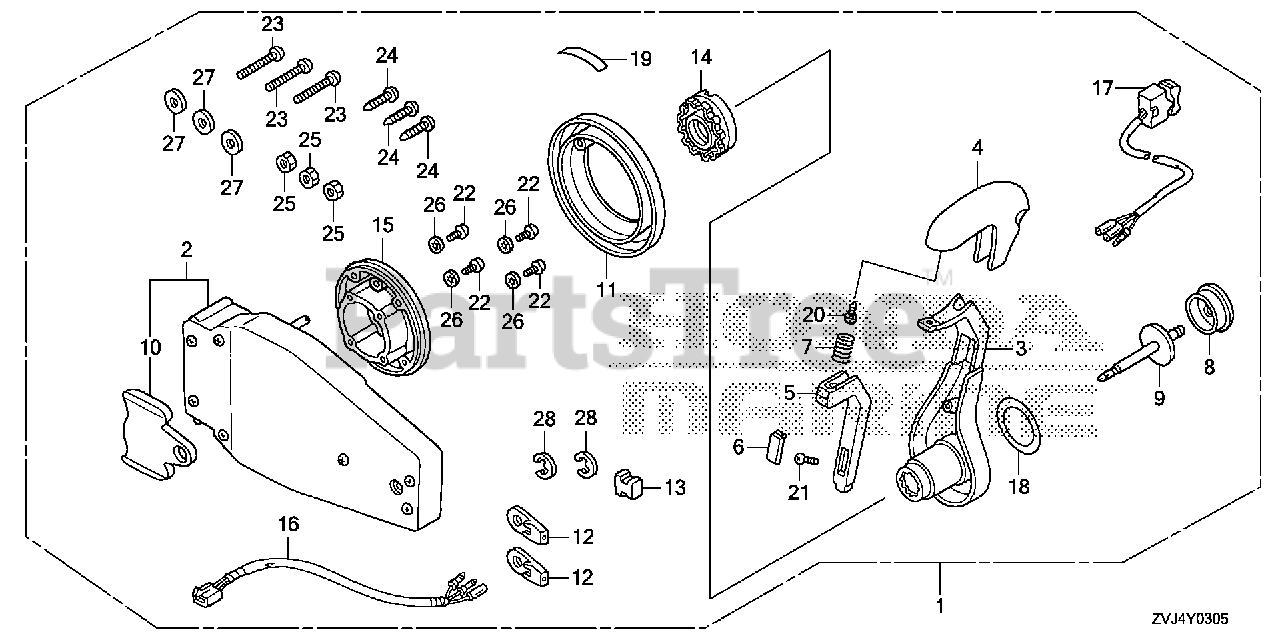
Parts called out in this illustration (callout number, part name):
1	BOX KIT, REMOTE CONTROL (FLUSH MOUNT)(L)
2	HOUSING ASSY., L. (INNER) (FLUSH MOUNT)
3	HANDLE, REMOTE CONTROL
4	COVER, GRIP
5	ARM, NEUTRAL LOCK
6	COVER, LOCK ARM
7	SPRING, NEUTRAL LOCK ARM
8	BUTTON, THROTTLE
9	SHAFT, THROTTLE BUTTON
10	PLATE, DWELL
11	COVER ASSY.
12	TERMINAL, CABLE
13	SPACER, CABLE CLAMP
14	HOLDER, NEUTRAL LOCK
15	BASE
16	SUB-HARNESS ASSY., POWER TRIM-TILT (C)
17	SWITCH ASSY., POWER TRIM-TILT (C)
18	MARK, HANDLE FLUSH MOUNT
19	MARK, FLUSH MOUNT
20	SCREW, PAN (5X16)
21	SCREW, TRUSS (4X12)
22	SCREW, PAN (5X30)
23	SCREW, PAN (6X35)
24	SCREW, TAPPING (6X30)
25	NUT, HEX. (6MM)
26	WASHER, LOCK (5MM)
27	WASHER, PLAIN (6MM)
28	E-RING (6MM)
